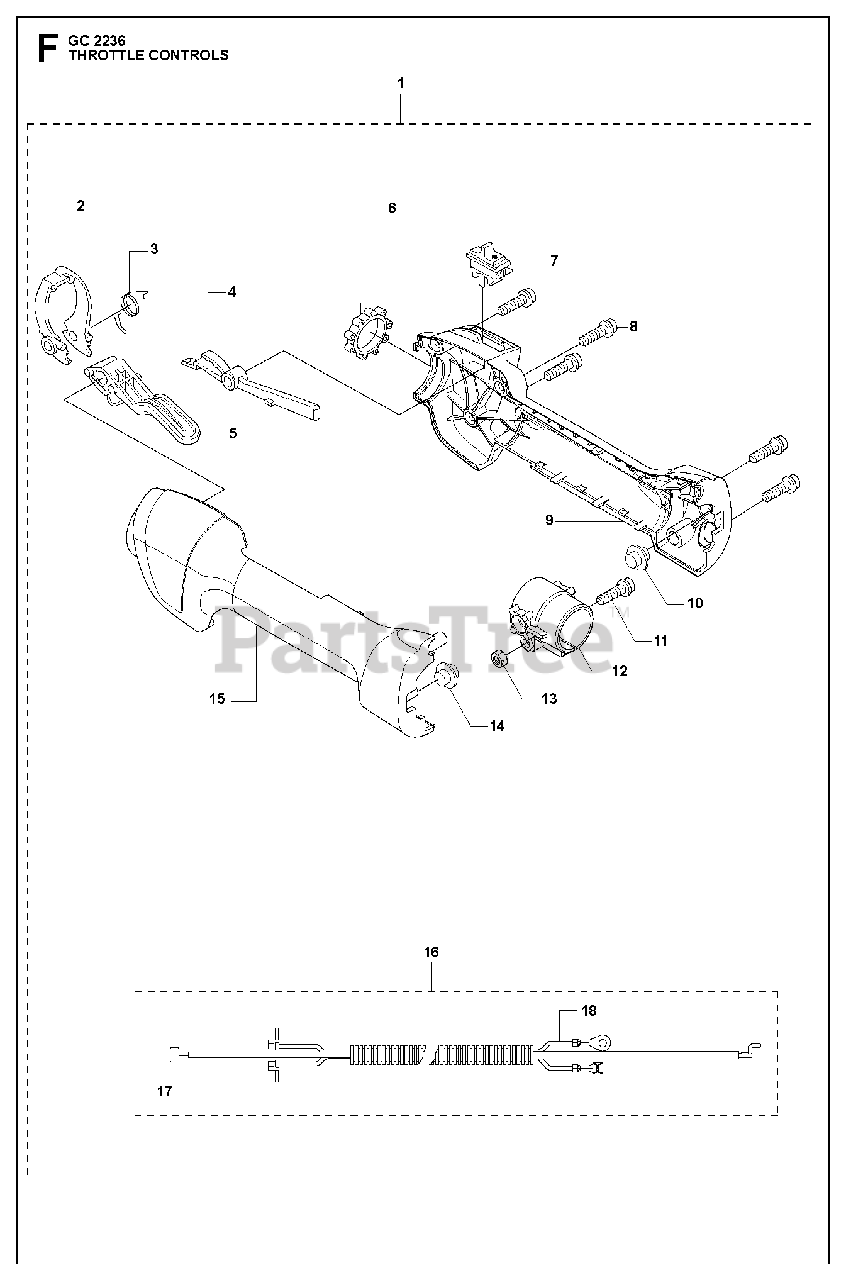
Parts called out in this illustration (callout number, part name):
2	LEVER
3	RETURN SPRING
4	THROTTLE LOCK
5	THROTTLE TRIGGER
6	VIBRATION DAMPER
7	STOP BUTTON
8	SCREW
9	HANDLE HALF
10	VIBRATION ABSORBER
11	SCREW
12	HOLDER
13	NUT
14	VIBRATION ABSORBER
15	HANDLE HALF
16	WIRING ASSY.
17	THROTTLE WIRE ASSY
18	SHORT CIRCUIT CABLE
